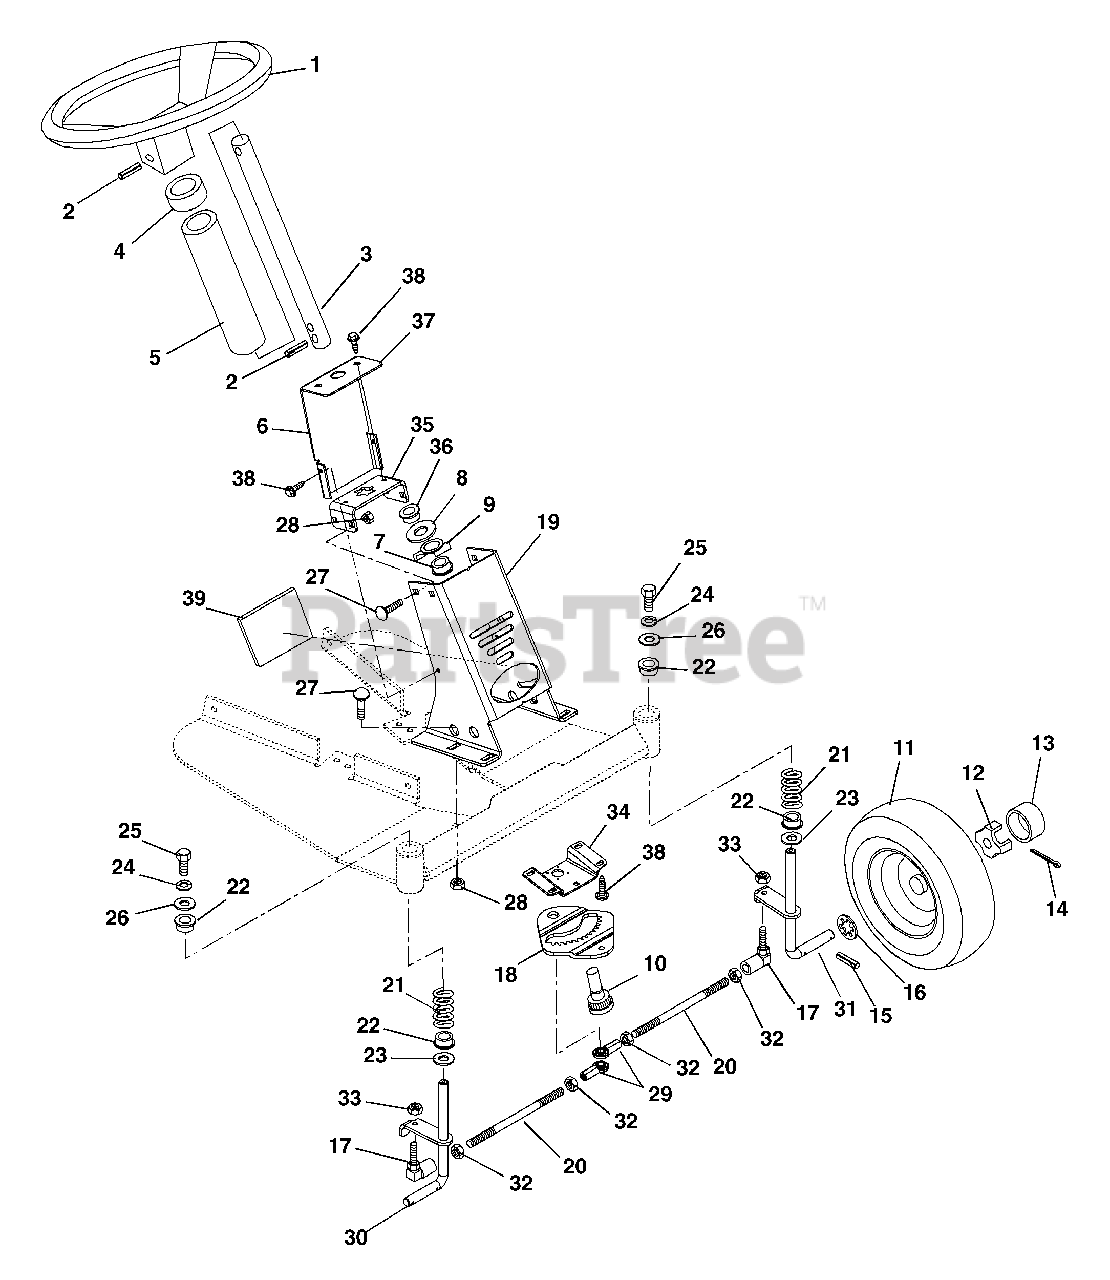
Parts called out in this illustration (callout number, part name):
1	Steering Wheel 13 Inch
2	Pin, Roll .25 x 1.75
3	Steering Shaft
6	Pin, Roll .188 x 1.00
7	Bushing, Flange .625 x 1.156 x .375
8	Washer, Hardened Steel .515 x .97 x .062
9	Retaining Plate1
10	Pinion
11	Tire/Wheel Assembly
11	Tire 4.10/3.50 - 4
11	Bushing, Flange .75 x 1.38 x .75 x 1.557
11	Wheel
12	Spindle Cup
13	Hub Cap
14	Pin, Cotter .12 x 1.00
15	Pin, Groove .25 x 1.25
16	Spindle Washer
17	Ball Joint
18	Steering Gear
19	Box, Steering
20	Steering Link
21	Spring, Suspension
22	Bushing 1.00 x .75 x 1.00
23	Washer, Flat Steel .812 x 1.50 x .135
24	Washer, Locking .31 x .078 Regular
25	Bolt, Hex .31-18 x .75 Grade 5
26	Washer, Flat Steel .344 x 1.38 x .075
27	Bolt, Round Head Square Neck .38-16 x .75 Grade 5
28	Nut, Locking Top Flange .38-16
29	Rod End, .38 Right Hand
30	Weldment, Spindle Right Hand
31	Weldment, Spindle Left Hand
32	Nut, Locking Center .875-9
33	Nut, Locking Nylon .375-24 With Insert
34	Steering Gear Support
35	Bracket, Steering Column
36	Bushing, Flange
37	Support, Steering Column
38	Screw, Tapping 10-24 x .375 TORX Pan Head
